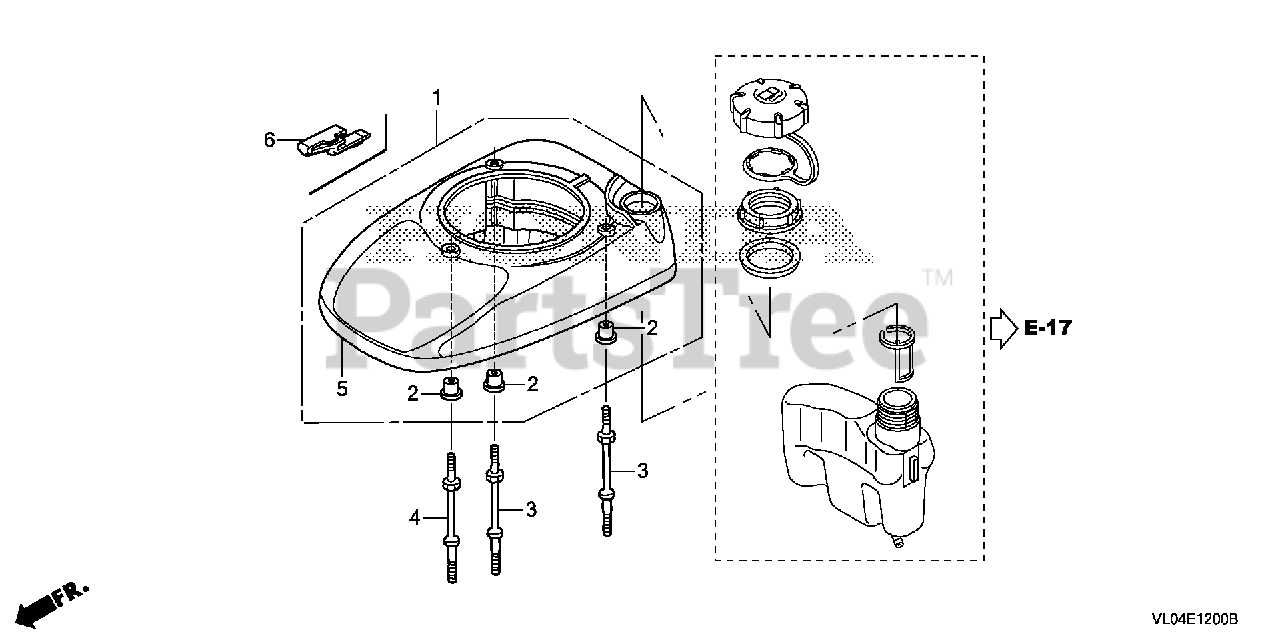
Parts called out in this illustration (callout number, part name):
3	BOLT, STUD (FAN COVER)
4	BOLT, STUD (FAN COVER)
5	COVER, FAN *R280* (POWER RED)
6	CLIP, TANK MOUNTING *R280* (POWER RED)
